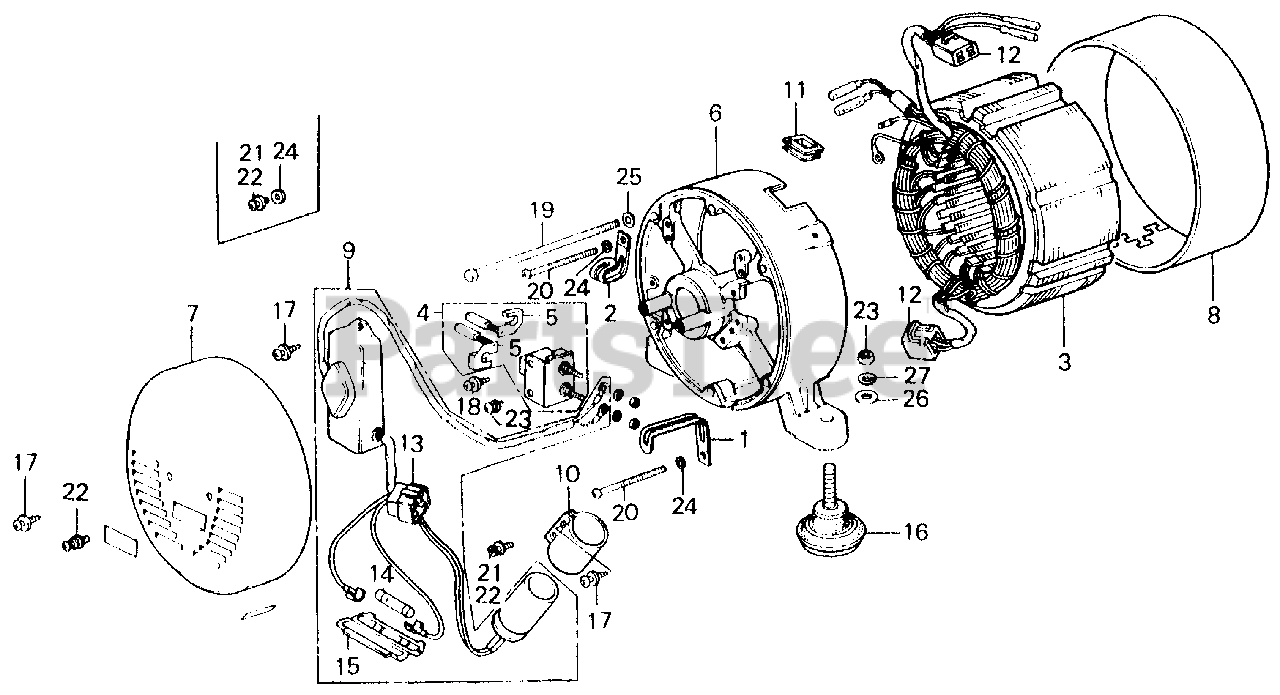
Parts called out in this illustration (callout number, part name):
1	CLAMP A, WIRE
2	CLAMP B, WIRE
3	STATOR ASSY.
4	HOLDER, BRUSH
6	HOUSING, RR. *R8* (BRIGHT RED)
6	HOUSING, RR. *R8* (BRIGHT RED) (NOT AVAILABLE)
7	COVER, GENERATOR END *R8* (BRIGHT RED)
8	COVER, STATOR *R8* (BRIGHT RED)
9	REGULATOR ASSY., AUTOMATIC VOLTAGE
9	REGULATOR ASSY., AUTOMATIC VOLTAGE (NOT AVAILABLE)
12	CONNECTOR, FEMALE (4 POLE)
13	CONNECTOR, MALE (4 POLE)
14	FUSE (2.5A)
15	HOLDER, FUSE
16	RUBBER (LOWER)
17	SCREW, TAPPING (5X12)
18	SCREW, TAPPING (5X14)
19	BOLT, HEX. (6X142)
19	BOLT, HEX. (6X142) (SOURCE: VINTAGE PARTS INC.)
20	SCREW, PAN (5X60) (NOT AVAILABLE)
21	SCREW-WASHER (5X16)
22	SCREW-WASHER (5X10)
23	NUT, HEX. (8MM)
23	NUT, FLANGE (8MM)
24	WASHER, PLAIN (5MM)
25	WASHER, PLAIN (6MM)
26	WASHER, PLAIN (8MM)
27	WASHER, SPRING (8MM)
